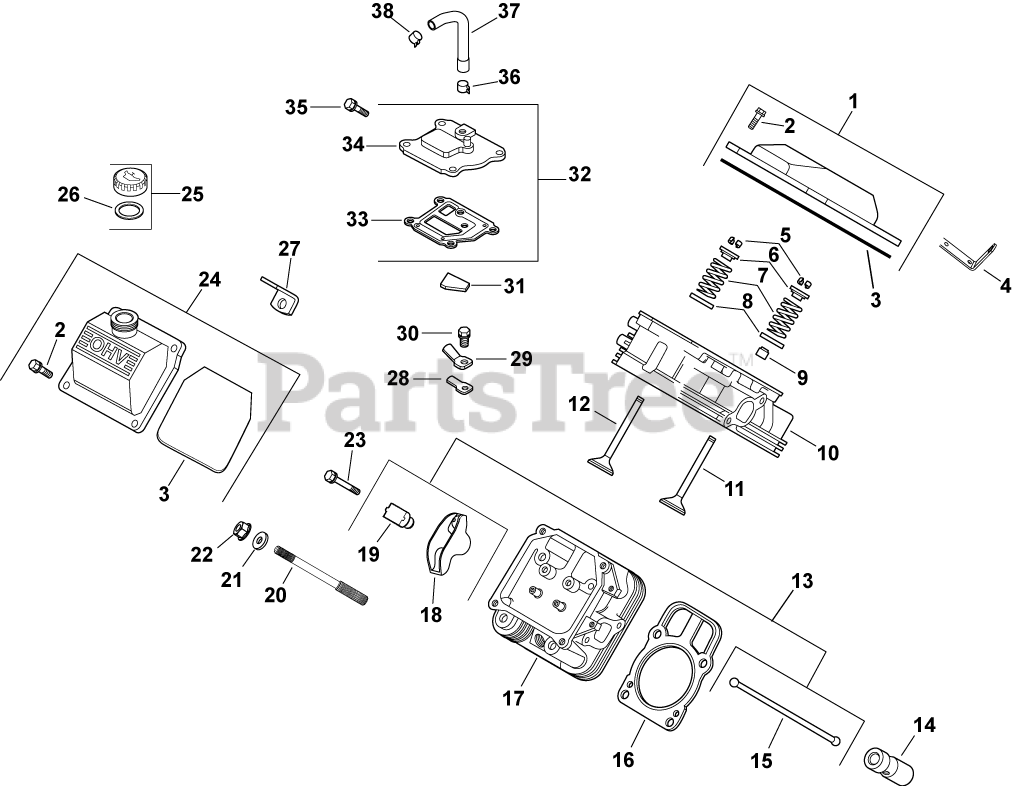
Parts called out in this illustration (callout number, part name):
1	KIT, VALVE COVER-PLAIN
2	SCREW, FLG M6X1.0X30
3	O-RING (YELLOW) -USE 24 153 30-S
4	STRAP, LIFTING-USE 25 445 03-S
5	KIT, RETAINER
6	RETAINER, VALVE SPRING - USE 25 173 28-S
7	SPRING, VALVE
8	RETAINER, SPRING
9	SEAL, VALVE STEM - (#2503214S)
10	HEAD, SERVICE ASSY CYL #1-USE 24 318 106
11	VALVE, INTAKE (STD)
12	VALVE, EXHAUST (STD) - USE 32 016 01-S
13	KIT, VALVE TRAIN
14	LIFTER, HYDRAULIC VALVE-USE 25 351 10-S
15	ROD, PUSH
16	CYL HEAD GASKET KIT-USE 24 841 04-S
17	HEAD, SERVICE ASSY CYL #2-USE 24 318 114
18	ARM, ROCKER
19	PIVOT, CYLINDRICAL ROCKER ARM-USE 24 599
20	STUD, M8X1.25
21	WASHER, FLAT 8.6 MM
22	NUT, FLG M8X1.25
23	SCREW, FLG M6X1.0X34
24	KIT, VALVE COVER-OIL FILL
25	KIT, OIL FILL CAP (BLACK)
26	O-RING, DIPSTICK
28	REED, BREATHER
29	RETAINER, REED
30	SCREW, FLG THD FRM M5X.8X10
31	FILTER, BREATHER-USE 24 050 11-S
32	KIT, BREATHER ASSEMBLY
33	GASKET, BREATHER-USE 24 041 67-S
34	COVER, BREATHER -USE 24 033 01-S
35	SCREW,FLG THD FRM M6X1.0X20-(#25086396S)
36	CLAMP, BAND SPRING HOSE-(#2523737S)
37	HOSE, BREATHER-USE 24 326 96-S
38	CLAMP, HOSE (KM)-USE 25 237 31-S
2401602-S	VALVE, EXHAUST (.25)
2401702-S	VALVE, INTAKE (.25)
